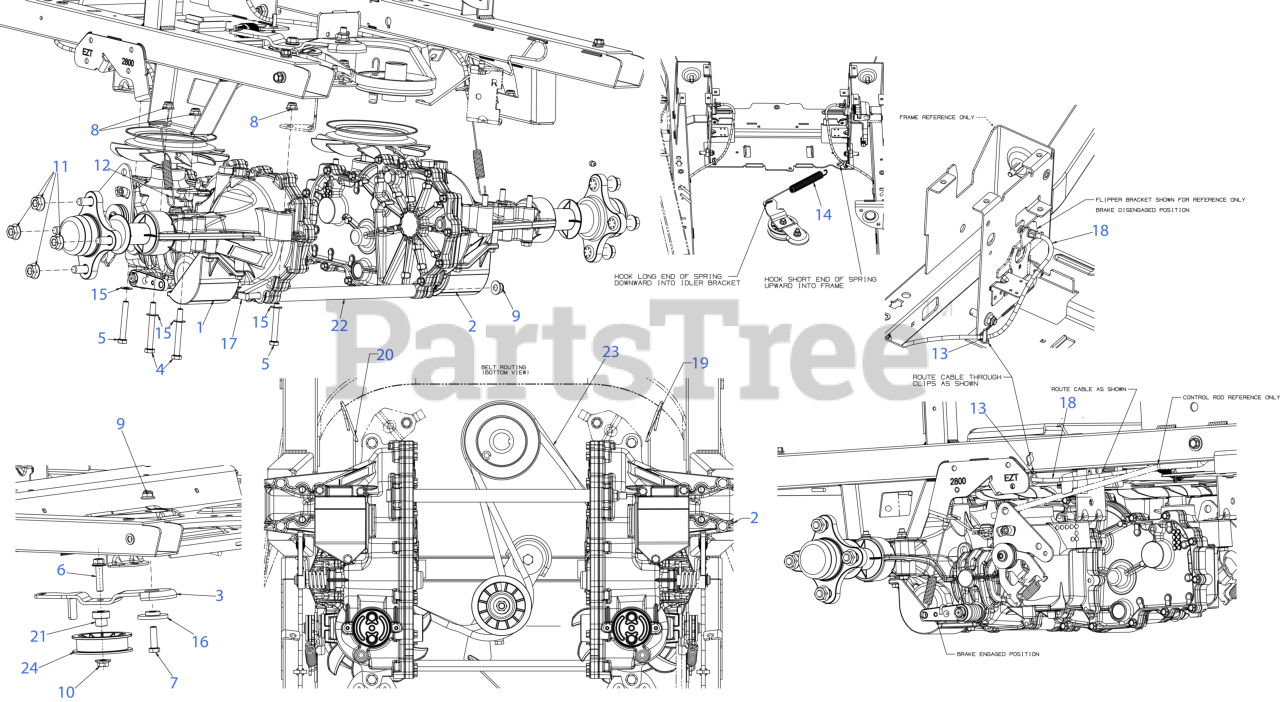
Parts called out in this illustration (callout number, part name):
1	HYDRO TRANSMISSION (LH)
2	HYDRO TRANSMISSION (RH)
3	HYDRO DRIVE IDLER BRACKET
4	HEX SCREW 5/16-18 x 2.75
5	HEX SCREW 5/16-18 x 2.25 GR5
6	HEX HEAD BOLT (3/8-16:1.50 GR8)
7	SCREW 3/8-16 x 1.25 GR5
8	FLANGE LOCK NUT 5/16-18
10	FLANGE LOCK NUT
11	HEX FLANGE NUT 7/16-14
12	BOW TIE COTTER PIN 1/4-5/16
13	CABLE RETAINER CLIP
14	EXTENSION SPRING .75 DIA X 10.27
15	FLAT WASHER
16	SHOULDER SPACER
17	SUPPORT TUBE ROD
18	PARK BRAKE CABLE
19	HYDRO BYPASS ROD (RH)
20	HYDRO BYPASS ROD (LH)
21	SHOULDER SPACER
22	SUPPORT TUBE
23	TRANSMISSION DRIVE BELT A x 67
23	Cub Cadet TRANS DRIVE BELT A x 67 RZT
23	Troy-Bilt TRANSMISSION DRIVE BELT
24	FLAT IDLER PULLEY 3.00 OD
